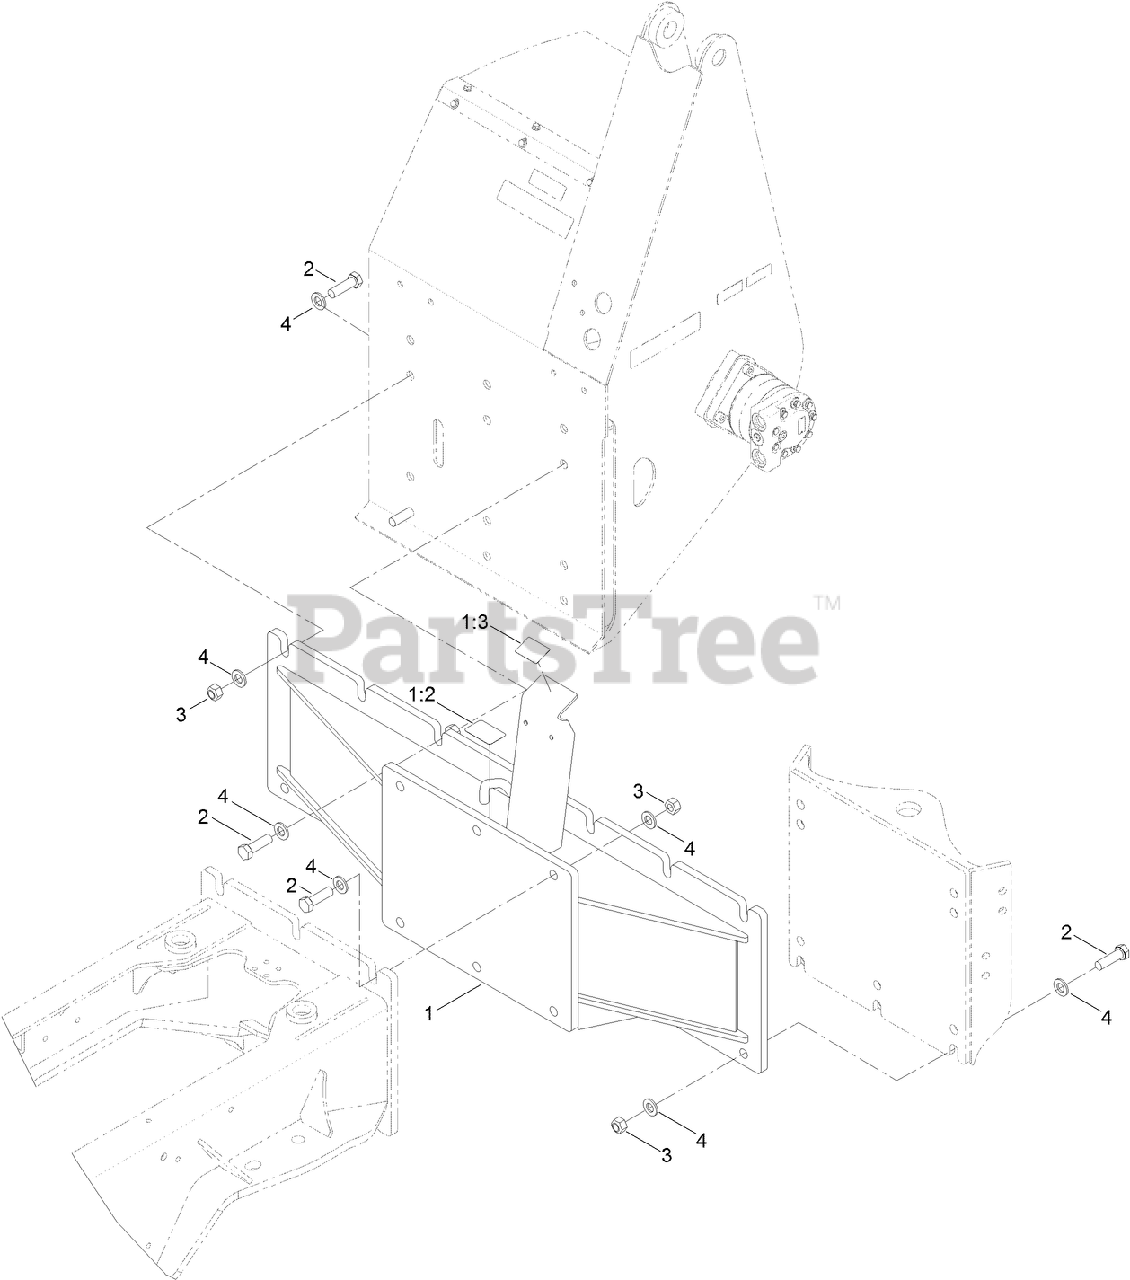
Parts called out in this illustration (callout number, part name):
1	RT600 COMBO MOUNT
1:2	DECAL-LIFT/TIE DOWN
1:3	DECAL-SELECTOR
3	NUT-LOCK
4	WASHER-Flat
